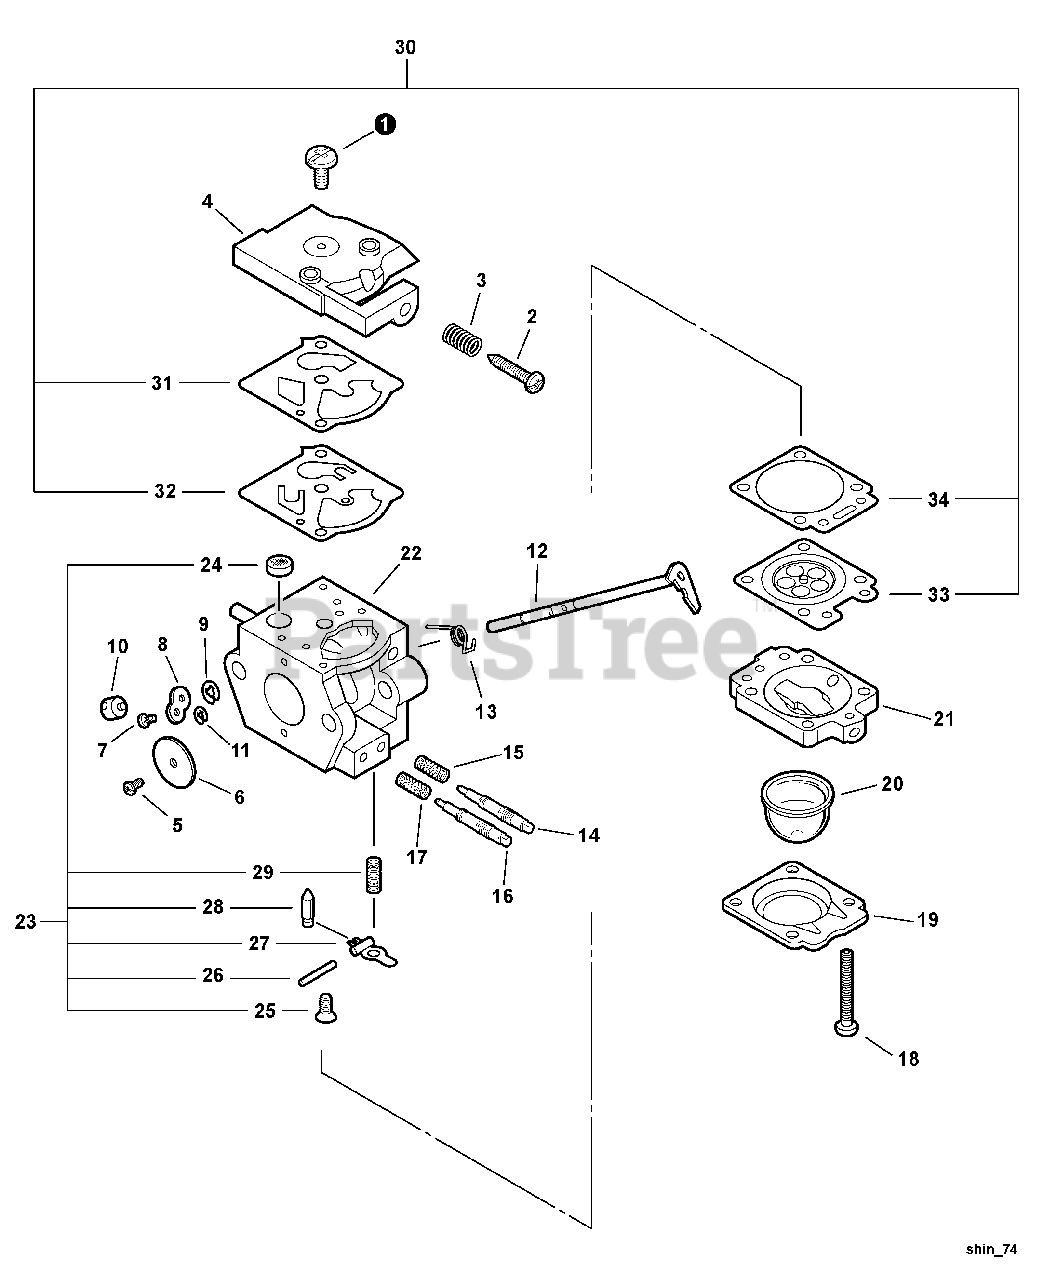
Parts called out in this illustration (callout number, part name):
1	SCREW, PUMP COVER
2	SCREW, IDLE ADJUST
3	SPRING, IDLE ADJUST
4	PUMP COVER ASSY
5	SCREW
6	VALVE, THROTTLE
8	LEVER, THROTTLE
9	RING, RETAINING
10	SWIVEL
11	RING, RETAINING
13	SPRING, RETURN
14	NEEDLE - LOW SPEED
15	SPRING
16	NEEDLE - HIGH SPEED
17	SPRING
19	RETAINER, PURGE BULB
20	BULB, PURGE
21	PURGE BASE ASSY
22	BODY, CARBURETOR
23	REPAIR KIT
24	STRAINER
25	SCREW, METERING LEVER PIN
26	PIN, METERING LEVER
27	LEVER, METERING
28	VALVE, INLET NEEDLE
29	SPRING, METERING LEVER
30	DIAPHRAGM/GASKET KIT
31	DIAPHRAGM, PUMP
32	GASKET, PUMP
33	DIAPHRAGM, METERING
34	GASKET, METERING
